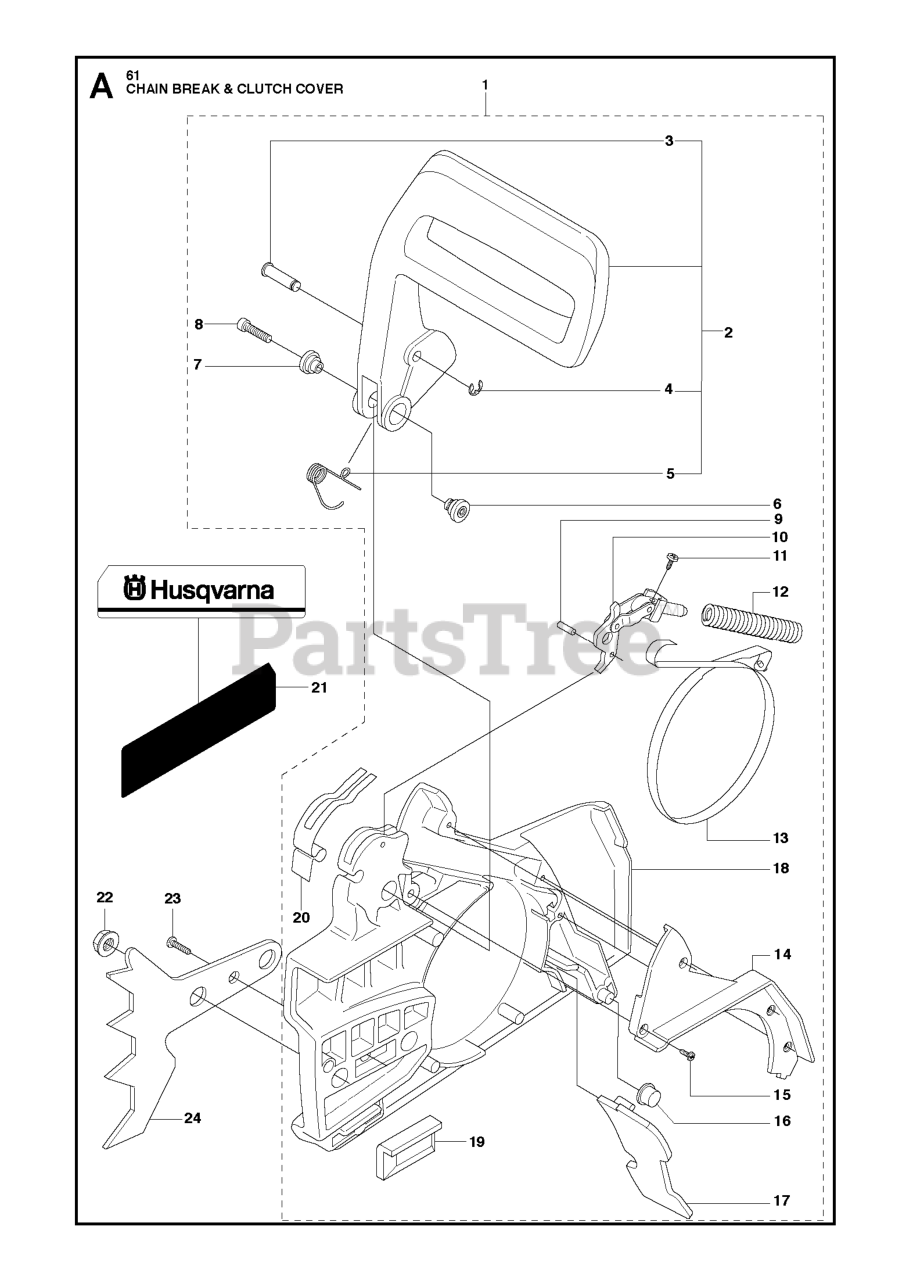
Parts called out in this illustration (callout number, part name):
1	CHAIN BRAKE
6	PIVOT SLEEVE L
7	PIVOT SLEEVE R
9	HARDENED PIN
12	BRAKE SPRING
13	BRAKE BAND
18	CLUTCH COVER
19	CHAIN GUIDE
22	NUT M8 FLANGE
23	SCREW MC6S 5X12
24	FELLING DOG
